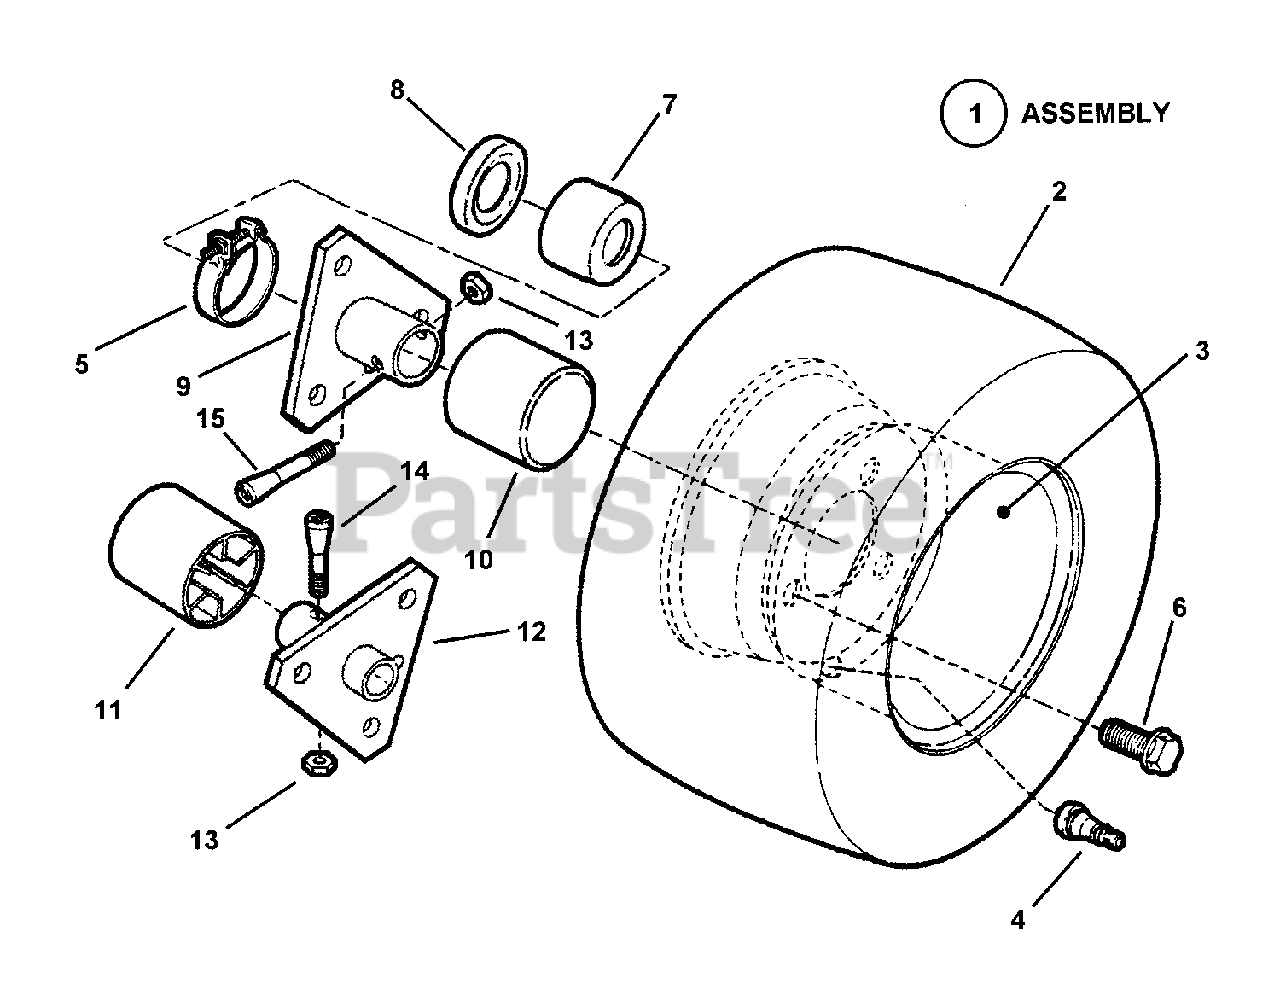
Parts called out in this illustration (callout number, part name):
1	ASSEMBLY, Rear Tire & Rim
2	TIRE, 16 x 6.50-8 (Kenda)
3	RIM, Extra Wide (For 16/7.50 x 8 Tire)
4	VALVE STEM, Snap In
5	CLAMP, Right Hand (for 2" Hose)
6	BOLT, 1/2-20 x 3/4" Lug, GR5
7	BOOT, Right Hand
8	SEAL, Oil
9	HUB, Rear Wheel RH, 3 Hole 1" ID
10	CAP, Hub
11	CAP, Hub, L. H. (Long Axle)
12	HUB, Rear Wheel LH, 3 Hole 3/4" ID
13	NUT, 5/16-24 Hex Lock, GR C
14	AXLE BOLT, 5/16-24 x 1-5/8" Tapered (Left Hand)
15	WHEEL BOLT, 5/16-24 x 2" Tapered (Right Hand)
